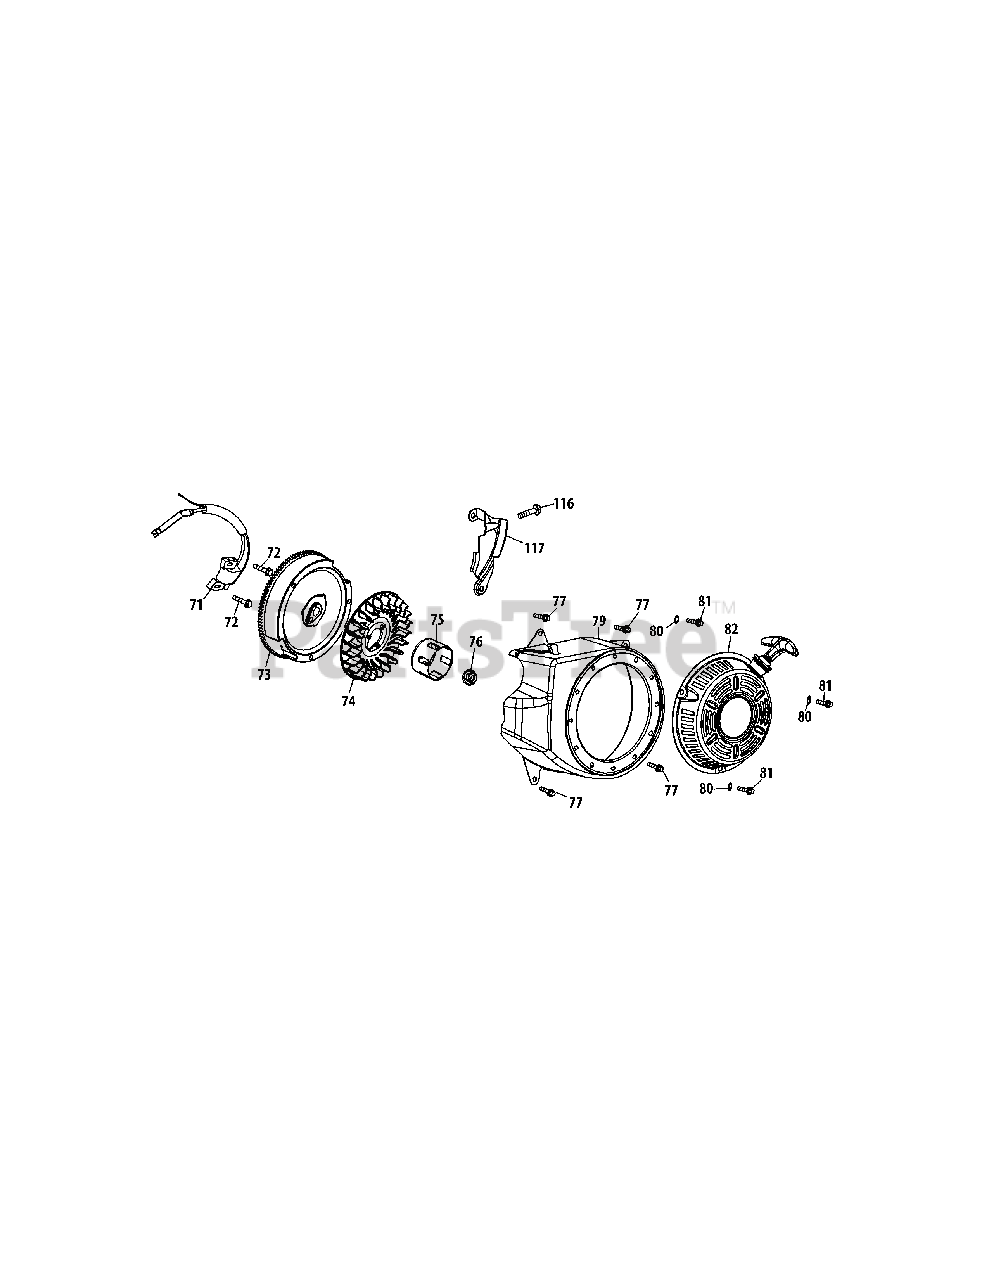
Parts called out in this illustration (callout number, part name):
71	Ignition Coil Assembly
72	Bolt M6×25
73	Flywheel
74	Fan, Cooling
75	Pulley, Starter
76	Nut, Special, M14×1.5
77	Bolt M6×12
79	Blower Housing
80	Flat Washer
81	Bolt M6×10
82	Recoil Starter Assembly
116	Bolt M6×18
117	Blower Housing Shield
